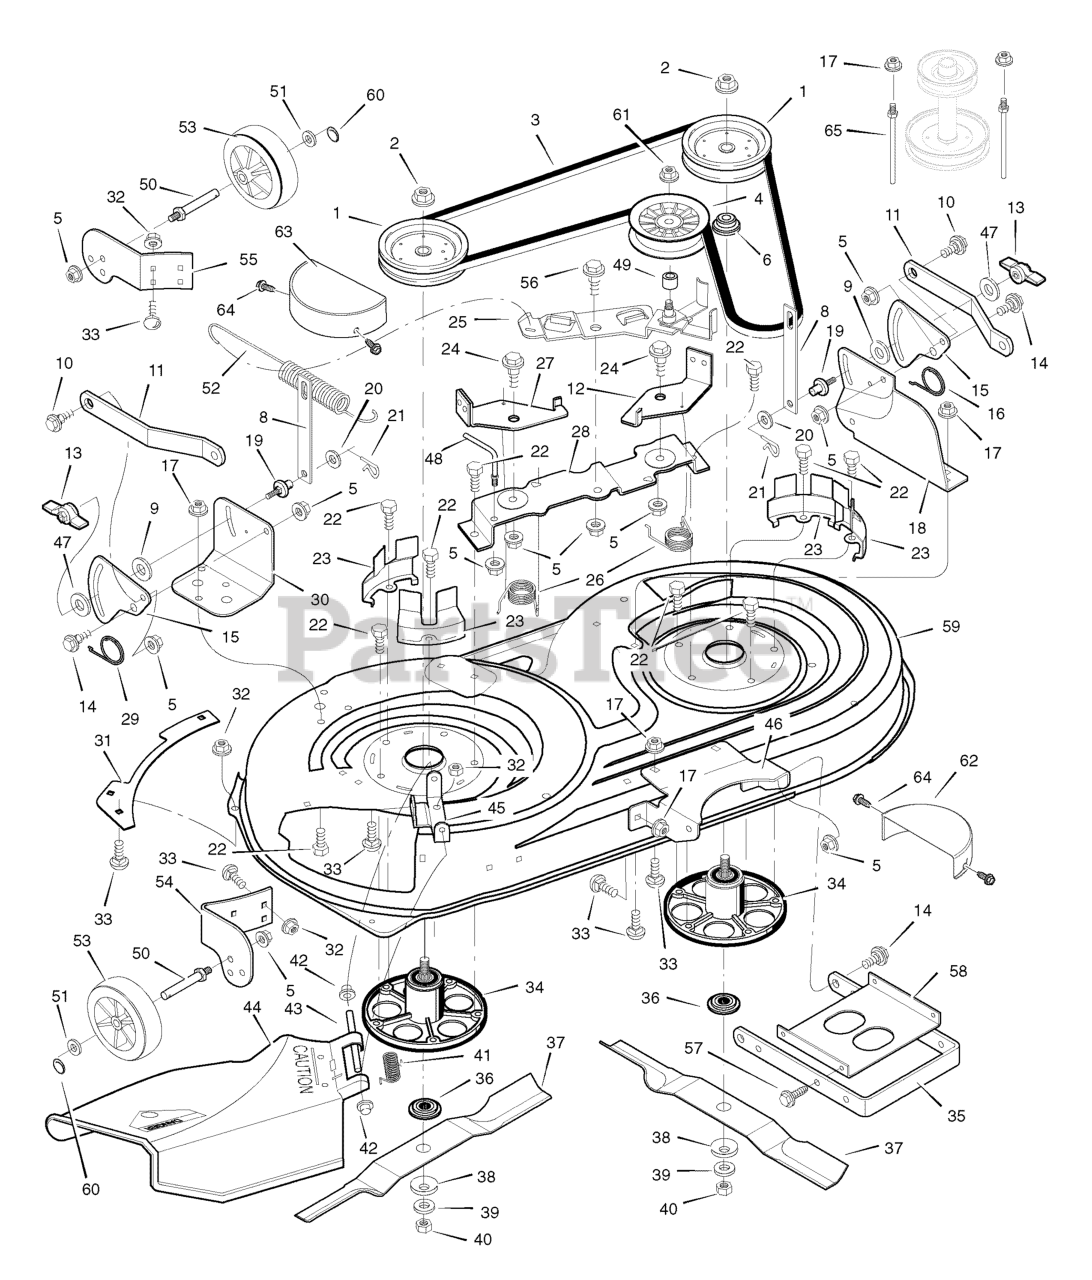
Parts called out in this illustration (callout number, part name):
1	Pulley, Jackshaft
2	Nut, Hex
3	Belt, Mower Drive
4	Pulley, Idler
5	Nut, Flange
6	Spacer, Pulley
8	Link, Lift
9	Pad, Friction
10	Bolt, Shoulder
11	Bracket, Suspension
12	Pad Assembly, Left Brake
13	Knob
14	Bolt, Shoulder
15	Plate, Suspension
17	Nut, Flange
18	Bracket, Suspension
19	Pin, Hanger
21	Pin, Hair
23	Cover, Pulley
24	Bolt, Shoulder
25	Arm, Idler
27	Pad Assembly, Right Brake
28	Bracket, Brake
30	Bracket, Suspension
32	Nut, Flange
33	Bolt, Carriage
34	Mandrell Housing
35	Bracket, Suspension
36	Adapter, Blade
37	Blade
42	Cap, Push On
43	ROD, Deflector
44	Deflector Assembly
45	Bracket, Deflector Hinge
46	Bracket, Front Hanger
48	Guide, Belt
50	BOLT, Gauge Wheel
52	Spring, Extension
53	Wheel, Gage
54	Bracket, Right Wheel
55	Bracket, Left Wheel
56	Bolt, Shoulder
59	Housing, Blade, Complete (NO LONGER AVAILABLE)
59	Housing, Blade (Housing Only)
60	Ring, Locking
61	Nut, Flange
62	COVER, Pulley L.H.
63	GUARD, Belt R.H.
65	Guide, Belt
